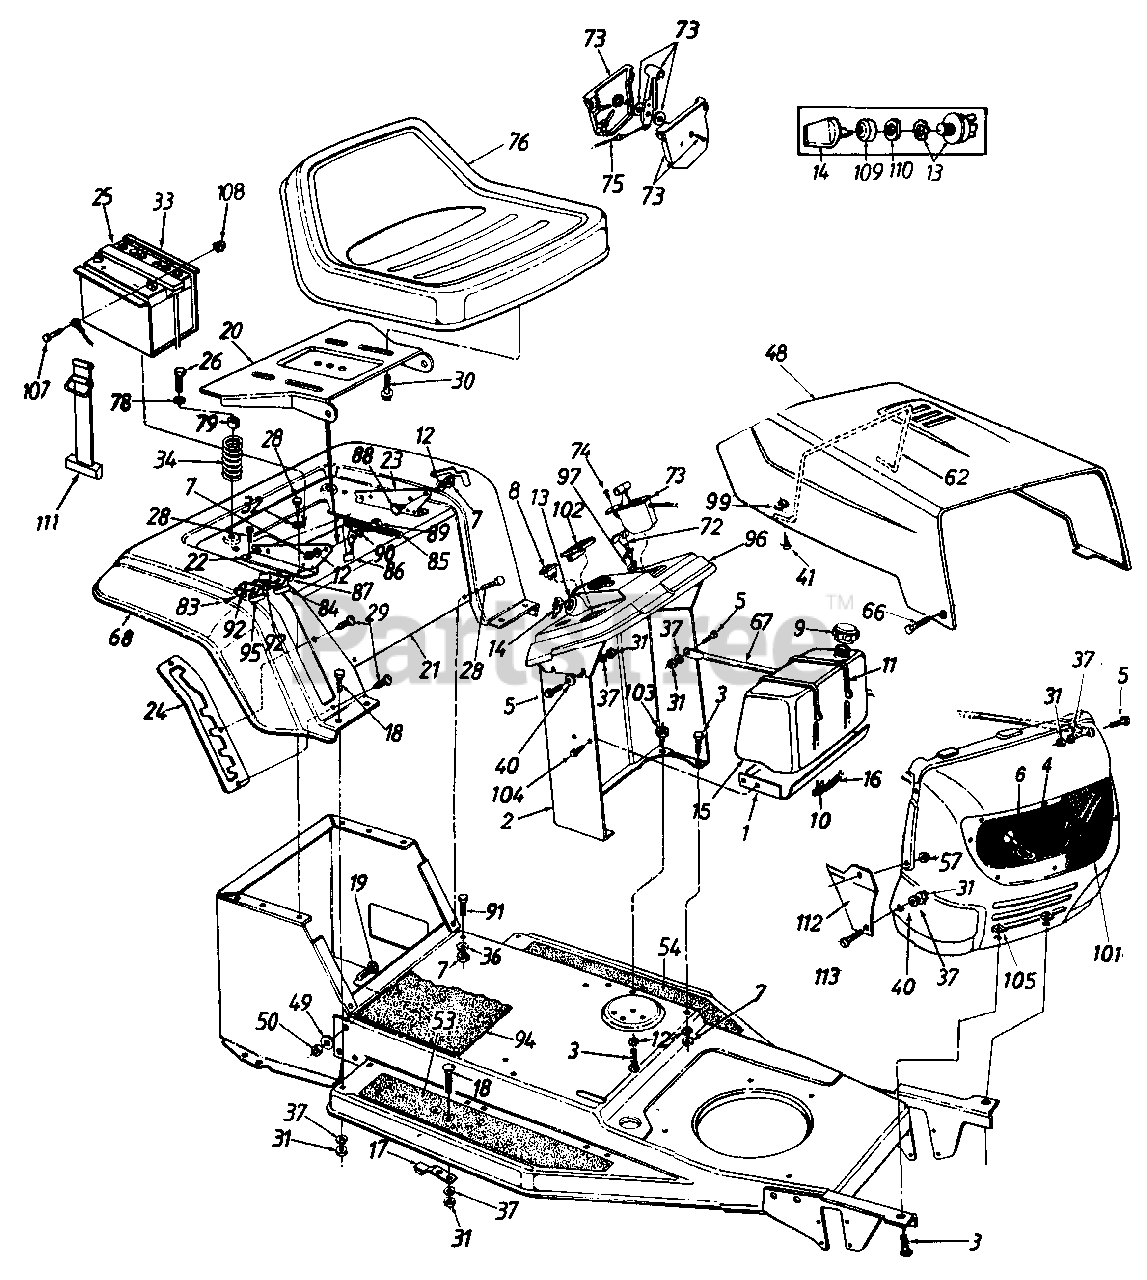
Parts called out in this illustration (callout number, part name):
4	Bulb
5	Hex Bolt 1/4 x .62" Lg.
6	Socket
7	Hex Nut 5/16-18 Thd.
8	Light Switch
9	Gas Cap
11	Cable Tie
12	L-Wash. 5/16" I.D.
13	Ignition Switch
15	Fuel Tank
16	Gas Line 15" Long
17	Blade Brake Ass'y.
18	Carriage Bolt 1/4-20 x .62"
19	Ribbed Neck Bolt 3/8-24 x .8"
25	Battery
26	Hex Self-Tap Screw 5/6-18 x 1.25" Lg.
27	Truss Mach. Scr. 1/4-20 x .75" Lg.
28	Hex AB-Tap Scr. 5/16 x .75" Lg.
29	Torx Mach. AB-Tap Scr. 1/4 x .62" Lg.
30	Hex Self-Tap Scr. 3/8-16 x .62" Lg. (Gr. 5)
31	Hex Nut 1/4-20 Thd.
32	External L-Wash. 5/16" I.D.
34	Compression Spring
36	Bell-Wash. 5/16" I.D.
37	L-Wash. 1/4" I.D.
40	Bell-Wash. .265" I.D. x .75"
41	Pan Hd. Scr. 10-24 x .75" Lg.
42	Fl-Wash. .218" I.D. x .62"
48	Hood
49	L-Wash. 3/8" I.D.- H.D.
50	Hex L-Nut 3/8-24 Thd.
52	Truss Mach. Scr. #10-24 x .5" Lg.
53	Foot Pad - R.H.
54	Foot Pad - L.H.
57	Lock Nut 1/4-20 Thd.
64	Hex Sems Nut #10-24 Thd.
65	Spr. Wash. .39" I.D. x .62" O.D.
66	Shld. Bolt
72	Choke Control
73	Throttle Control Box
74	Truss AB-Tap Scr. #10 x .5"
75	Throttle Wire
76	Seat Assembly
78	Fl-Wash. .344" I.D. x .88" O.D.
83	Hex Tap Scr. 08 x .5" Lg.
84	Safety Switch (Inner)
85	Ext. Spring 5.31" Lg.
86	Seat Lift Brkt.
87	Insulator Boss Plate
88	Shld. Bolt .437" Dia. x .162" Lg.
89	Shld. Bolt .437" Dia. x .268" Lg.
90	Spr. Wash. .445" I.D. x .75" O.D.
91	Hex Wash. Hd. Scr. 5/16-18 x .62" Lg.
92	Insulator Plate
94	Center Foot Pad
95	Safety Switch (Outer)
96	Dash Panel
97	Retainer Clip
98	Truss Mach. B-Tap Scr. #10 x .5" Lg.
99	Speed Nut
100	Internal Cotter Pin 5/16" Dia.
101	Lens
102	Ammeter
103	Hex Jam Nut 5/16-18 Thd.
104	Hex Wash. Hd. Tap Scr. 1/4-20 x .5" Lg.
105	U-Nut 5/16-18 Thd.
106	Ext. L-Wash. 1/4" I.D.
107	Hex Bolt 1/4-20 x .75" Lg.
108	Hex Sems Nut 1/4-20 Thd.
109	Ignition Cap
110	Ignition Nut 5/8-32 Thd.
111	Battery Strap
112	Side Panel - R.H.
113	Pan Hd. Mach. Scr. 1/4-20 x .5" Lg.
